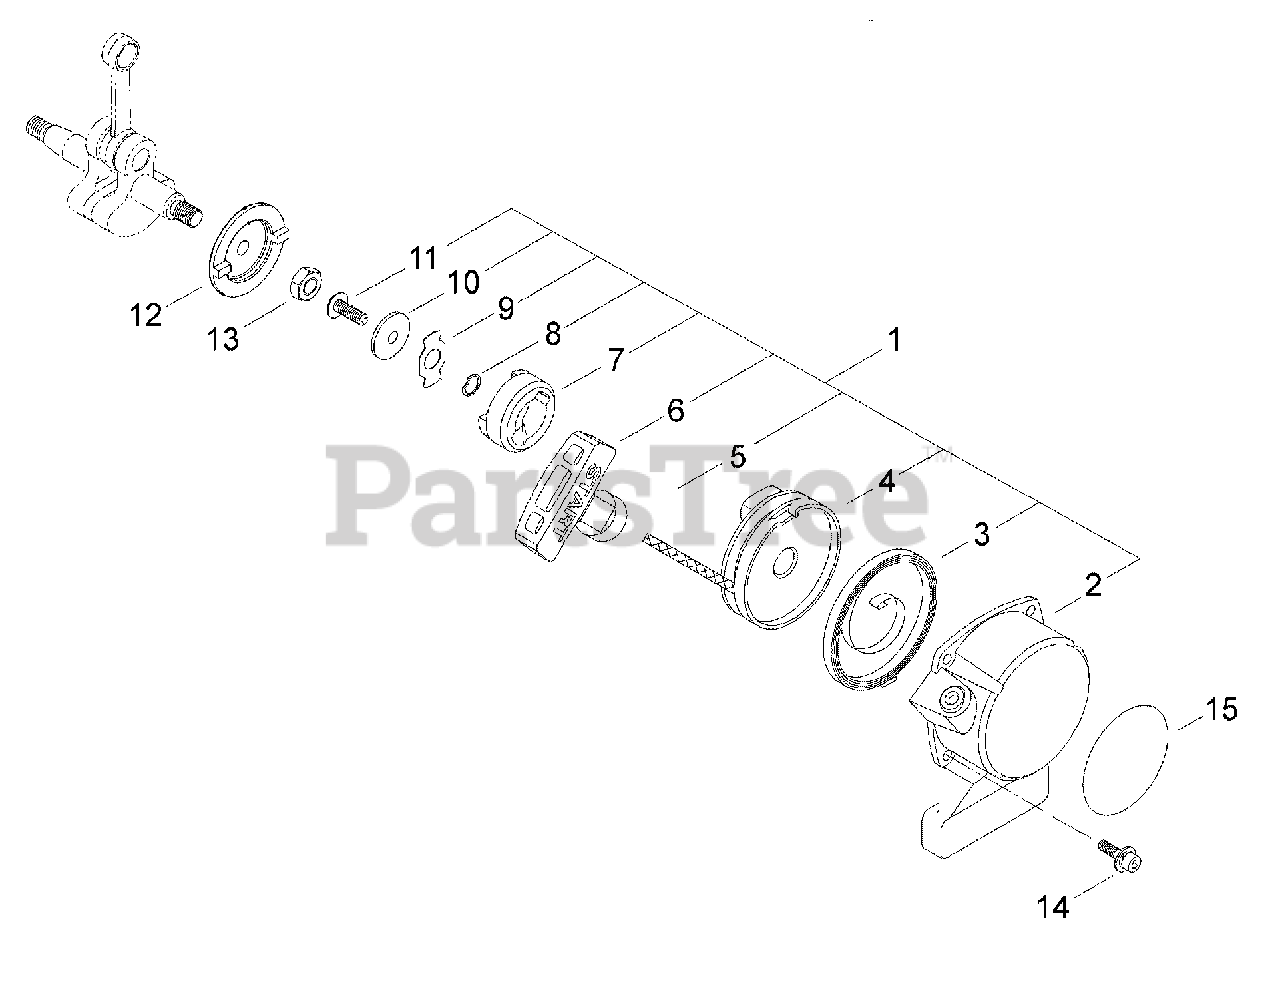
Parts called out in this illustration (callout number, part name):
1	STARTER ASSY
2	CASE, STARTER
3	SPRING, REWIND
4	REEL, ROPE
5	ROPE, STARTER
6	GRIP, STARTER
7	PAWL, STARTER
8	WASHER - SPRING
9	RETAINER
10	WASHER - 5
11	SCREW - 5
12	PAWL
13	NUT - 8
14	SCREW - 4X16
15	LABEL - E4
